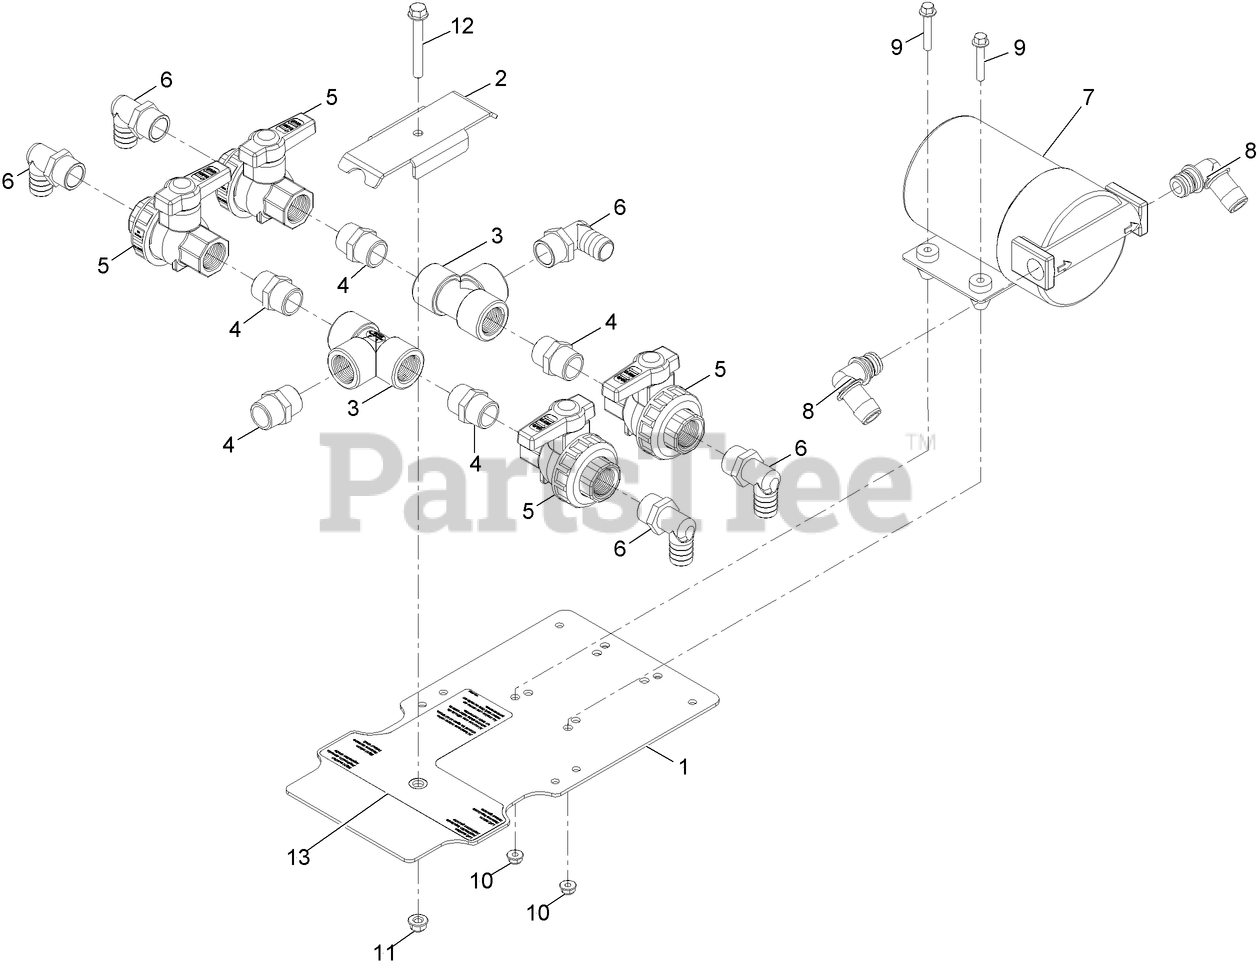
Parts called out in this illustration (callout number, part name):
1	MOUNT-PLATE, LIQUID VALVE
2	PLATE-CLAMP, LIQUID VALVE
3	FITTING-TEE
4	FITTING-NIPPLE
5	VALVE-UNION, 3/4
6	FITTING-ELBOW, 90
7	7.0 REMCO PUMP
8	FITTING-ELBOW
9	Screw-HHF
10	Nut-Hex Flange
11	Nut-Hex Flange
12	Screw-HHF
13	DECAL-VALVE, TANK
